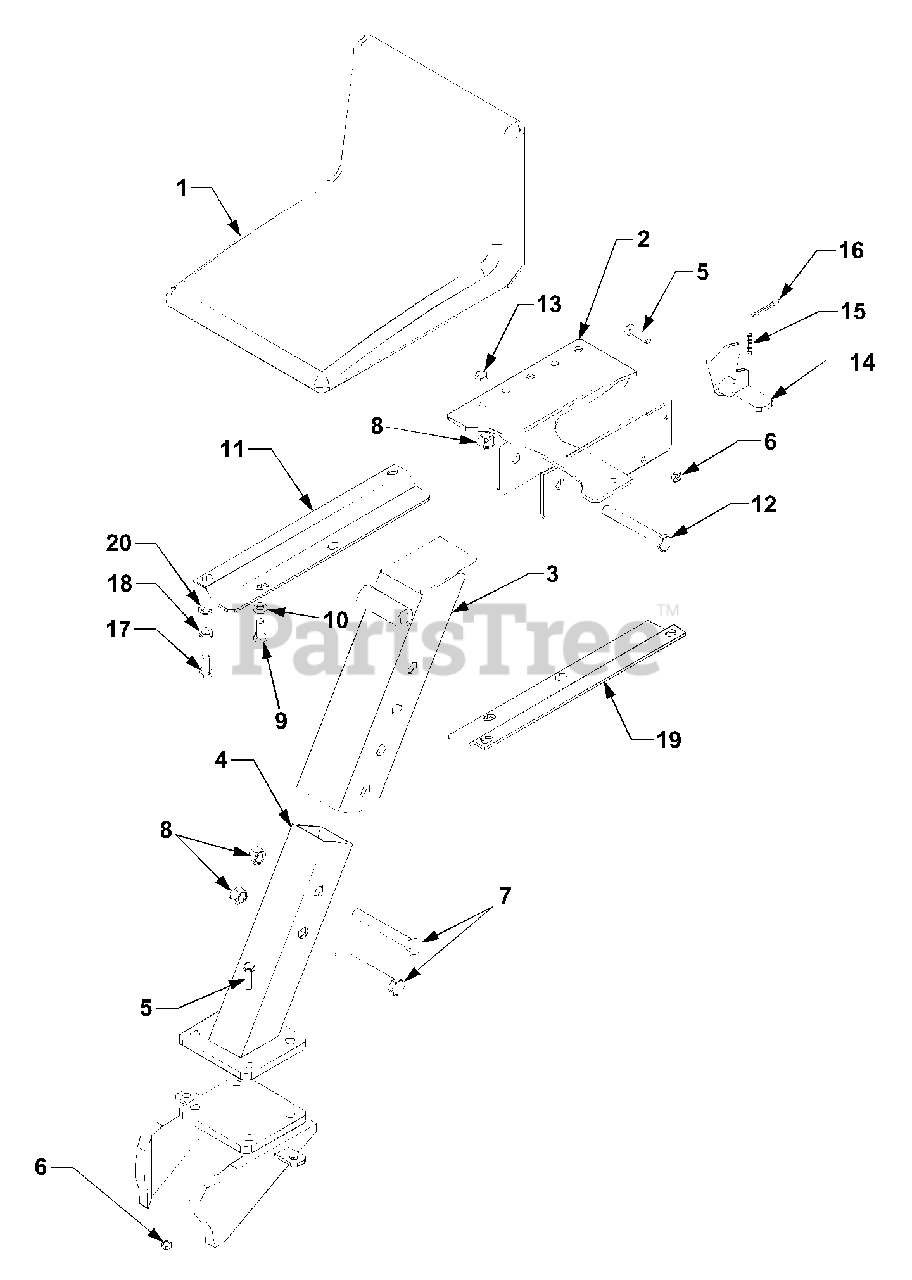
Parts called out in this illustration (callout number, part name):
5	Hex Head Screw, M10 x 30
6	Hex Head Screw, M10 Lock
7	Hex Head Screw, M12 x 80
8	Hex Nut, M12 Lock
9	Hex Head Screw, M8 x 20
10	Spring Washer
12	Hex Head Screw, M12 x 95
17	Hex Head Screw, 5/16-18
18	Spring Washer
19	Seat Rail, LH
